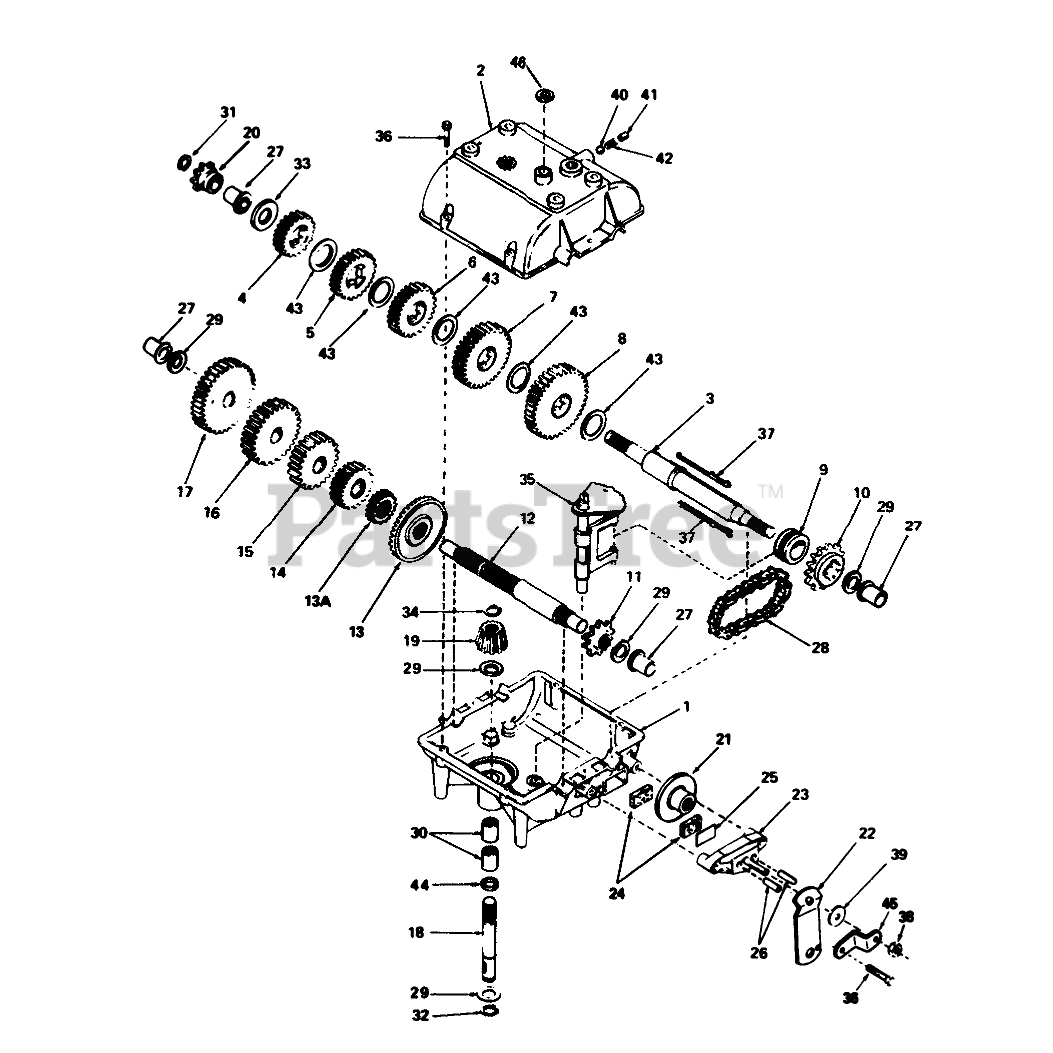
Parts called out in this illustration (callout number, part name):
1	Case-Transmission
2	Cover-Transmission
3	Shaft-Output
4	Gear-Spur 20 teeth
5	Gear-Spur (22 teeth)
6	Gear-Spur, 25 Teeth
7	Gear-Spur, 30 Teeth
8	Gear-Spur, 35 Teeth
9	Collar-Shift
10	Sprocket-18 Teeth
11	Sprocket-9 Teeth
12	Countershaft
13	Gear-Bevel (42Teeth)
13A	Gear-Spur 15 Teeth
14	Gear-Spur, 20 Teeth
15	Gear-Spur, 25 Teeth
16	Gear-Spur (28 teeth)
17	Gear-Spur (30 teeth)
18	Shaft-Input
19	Bevel Pinion-Input
20	Sprocket (8Teeth)
22	Lever-Brake
23	Nozzle-Carburetor
24	Brake Pad
25	Brake Pad Plate
26	Dowel Pin
27	Bushing-Flange
28	Chain-Roller #41
29	Washer
30	Bearing-Needle
31	Piston Asm (.020 O S)
32	Ring-Snap
33	Washer
34	Ring-Retainer
35	Rod and Fork ASM
36	Ring Set (.020 O S)
38	Locknut
39	Washer
40	Ball-Steel
41	Screw-Set
42	Spring
43	Washer
44	O Ring
45	Bracket
46	Cut Seal-Square
